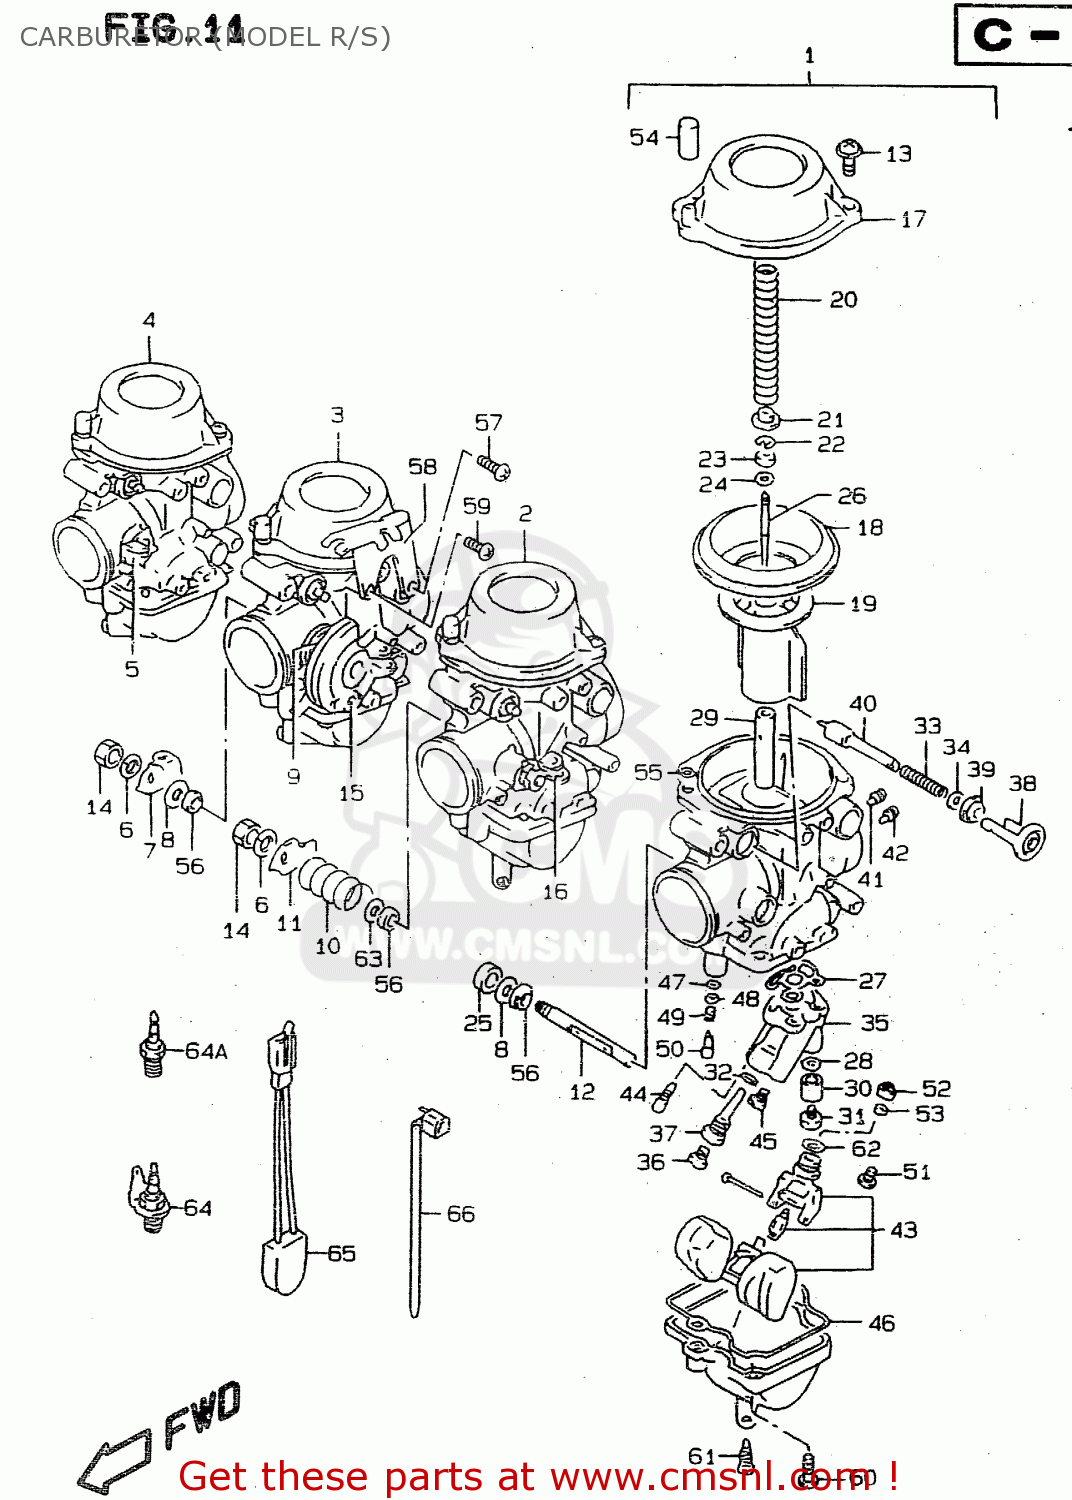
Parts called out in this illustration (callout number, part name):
1	CARBURETOR ASSY, LH
2	CARBURETOR ASSY, ML
3	CARBURETOR ASSY, MR
4	CARBURETOR ASSY, RH
5	SHAFT,THROTTLE
6	7
7	LEVER,THROTTLE
8	GASKET,THROTTLE SHAFT (NAS)
9	SPRING
10	SPRING
11	SHAFT,THROTTLE
12	SHAFT,THROTTLE
13	SCREW
14	NUT
15	SHAFT,THROTTLE
16	LEVER,THROTTLE
17	COVER,DIAPHRAGM
18	DIAPHRAGM
19	VALVE,PISTON
20	SPRING
21	RING
22	E RING
23	RING
24	WASHER
25	RING
26	NEEDLE JET (5DV1)
27	O RING
28	29
29	JET,NEEDLE(O-9)
30	RING
31	SCREW
32	O RING
33	SPRING
34	35
35	JET BLOCK ASSEMBLY
36	JET
37	HOLDER,JET
38	HOLDER,GUIDE
39	CAP,STARTER
40	PLUNGER ASSY
41	JET,MAIN AIR(0.8)
42	JET,PILOT AIR(120)
43	FLOAT/NEEDLE VALVE ASSY
44	JET,PILOT(12.5)
45	JET,STARTER(50)
46	SEAL
47	O RING,PILOT AIR SCREW
48	WASHER
49	SPRING
50	SCREW,PILOT
51	SCREW
52	FILTER
53	RING
54	CAP
55	O RING
56	SEAL
57	SCREW
58	BRACKET
59	SCREW
60	SCREW
61	SCREW,DRAIN
62	O-RING,NEEDLE VALVE
63	RING
64	HEATER ASSEMBLY,CARBURETOR
64A	HEATER,CARBURETOR (15W)
65	THERMO SWITCH,CARB HEATER
66	CLAMP(L:125)
